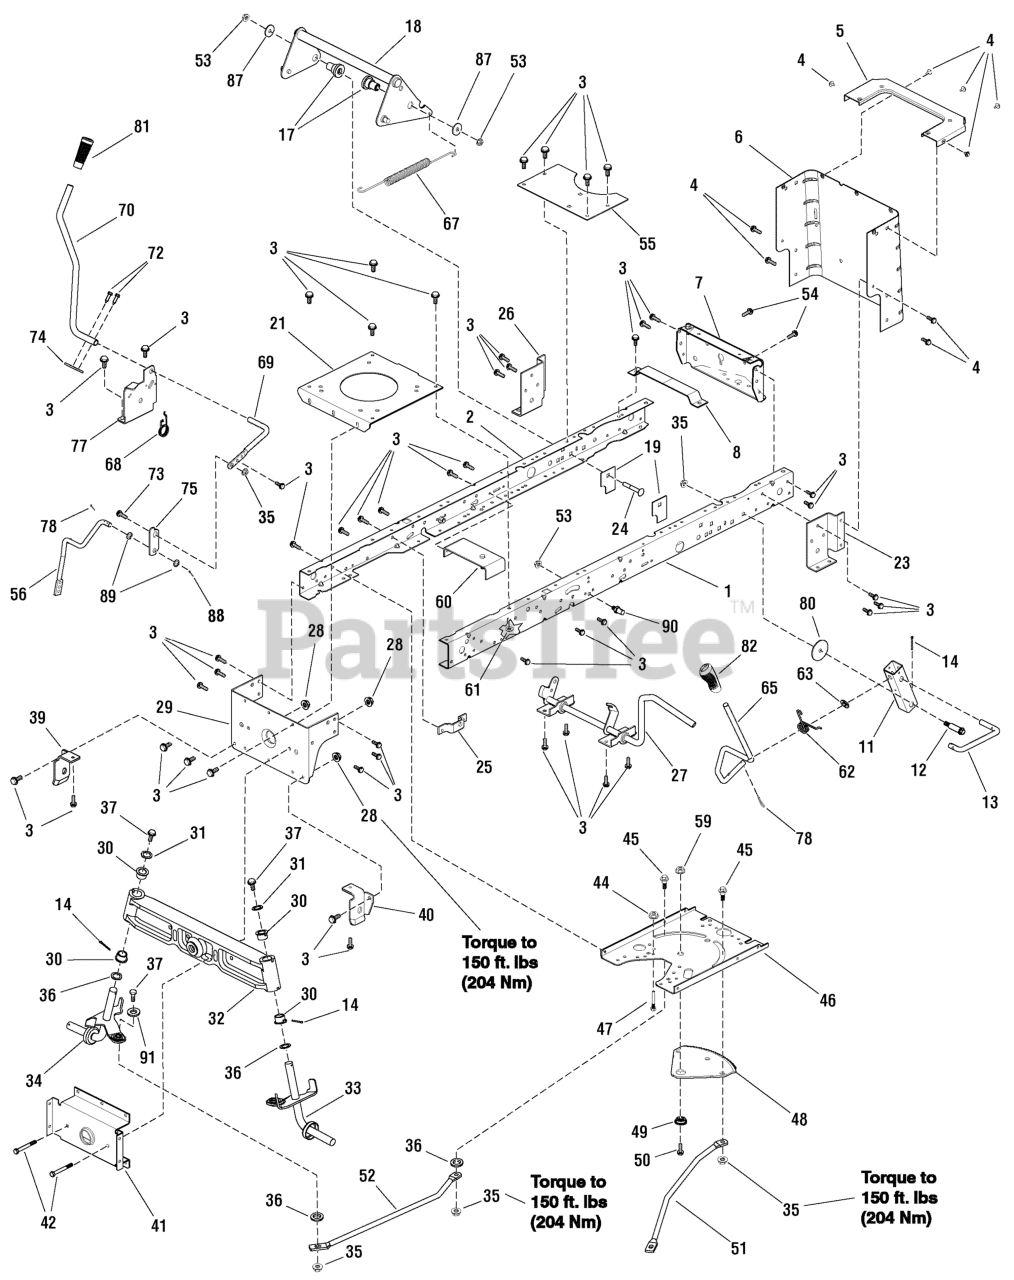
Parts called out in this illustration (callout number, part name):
1	FRAME, Left
2	FRAME, Right
3	CAPSCREW, 5/16-18 x 3/4
4	SCREW, Self Tap, SEMS, #10-24 x 1/2
5	TOP, Rear Plate
6	PLATE, Rear
7	PLATE, Hitch
8	BRACKET, Battery Support
11	BRACKET, Pivot
12	BOLT, Shoulder, 3/8-16 x 1/2
13	LINK, Lift Handle
14	COTTER PIN, 1/8 x 1-1/4
17	SPACER, Lifter
18	LIFTER ASSEMBLY
19	PLATE, Stiffening
21	PLATE, Engine
23	BRACKET, Left Transaxle
24	BOLT, Carriage, 3/8-16 x 2-1/2
25	BRACKET, Bellcrank
26	BRACKET, Right Transaxle
27	BRAKE PEDAL
28	NUT, Hex Flange, 5/16-24
29	BRACKET, Rear Hanger
30	BEARING, Spindle, LT
31	WASHER, Flat
32	AXLE, Cast Iron
33	SPINDLE, Left
34	SPINDLE, Right
35	NUT, Hex Flange 3/8-16
36	WASHER, Flat 3/8
37	BOLT, Hex 3/8-16 x 1-1/2
39	HANGER, Right Deck
40	HANGER, Left Deck
41	AXLE, Hanger
42	BOLT, Hex Head, 5/16-24 x 2-3/4
43	SECTOR GEAR ASSEMBLY
44	NUT, Hex Flange, 5/16-18
45	BOLT, Shoulder, 3/8-16 x 1
46	PLATE, Steering Mount
47	SCREW, Guide
48	GEAR, Sector
49	BEARING, Sector Gear
50	CAPSCREW, Hex Head, 5/16-18 x 1
51	DRAG LINK, Left
52	DRAG LINK, Right
53	NUT, Hex Flange, 3/8-16
54	SCREW, 3/8-16 x 3/4
55	PLATE, Idler Pulley, Hydro Gear
56	CRANK, PTO
59	NUT, Flange, 5/16-18
60	IDLER BRACKET ASSEMBLY, Secondary
61	NUT, Hex Flange, 5/16-18
62	SPRING, Torsion
63	WASHER, Flat, 1
65	HANDLE, Lift
67	SPRING, Extension
68	SRPING, Torsion
69	LEVER, PTO
70	HANDLE, PTO
72	SCREW, Thread Forming, 1/4-20 x 1
73	BOLT, Shoulder, 3/8-16 x 1/2
74	PADDLE, Switch, Yellow
75	LINK, PTO, Yellow
77	BRACKET, PTO
78	HAIR PIN
80	WASHER, Plain, 2-1/4
82	GRIP, 1/2" Shaft, Tapered
87	WASHER, 1-1/2
88	PIN, Cotter, 3/4
89	WASHER, Flat, 3/4
90	PIN, Threaded Shoulder, 3/8-16 x 1-1/2
91	WASHER, Flat, 25/64" ID x 1" OD
